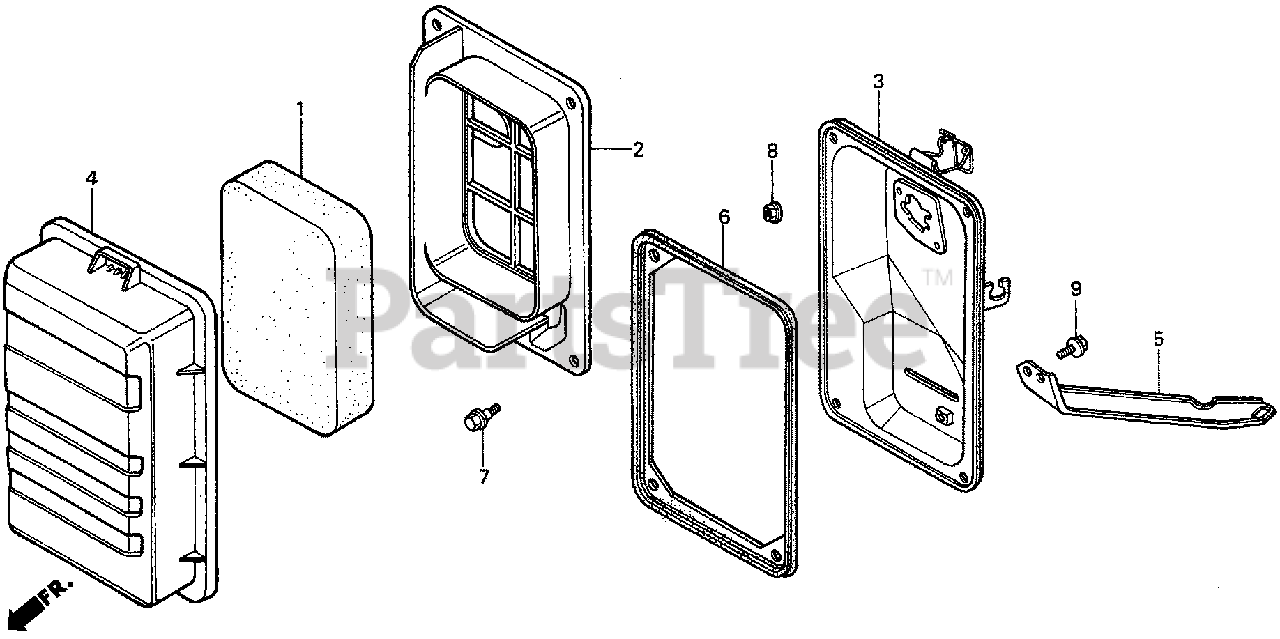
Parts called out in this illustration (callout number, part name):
1	ELEMENT, AIR CLEANER
2	SEPARATOR, AIR CLEANER
3	HOUSING, AIR CLEANER
4	COVER, AIR CLEANER
5	STAY, AIR CLEANER
6	SEAL, AIR CLEANER
7	BOLT, SETTING
8	NUT, FLANGE (6MM)
9	BOLT, FLANGE (6X8)
9	BOLT, FLANGE (6X10)
